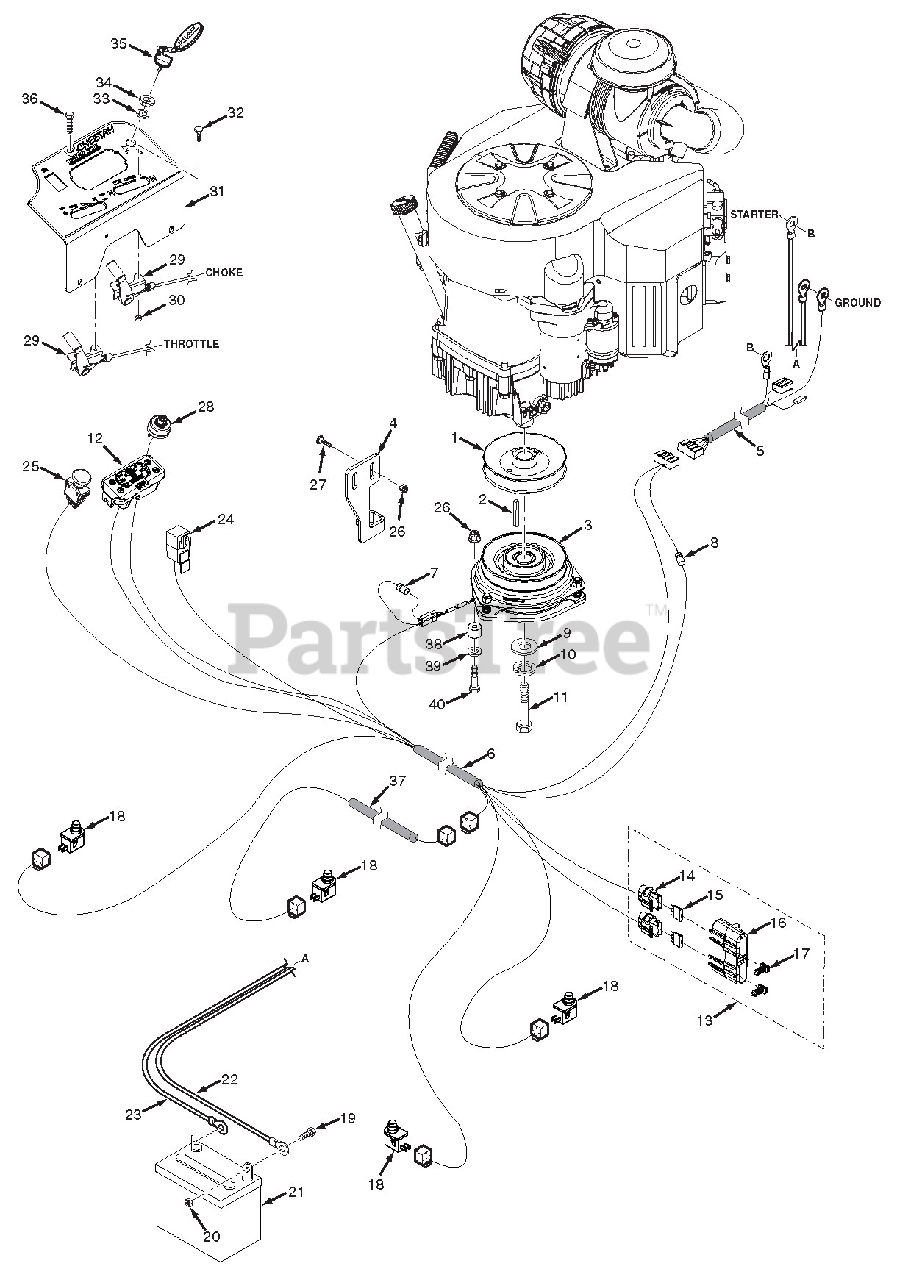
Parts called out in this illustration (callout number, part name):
1	Pulley, 5.80 Dia. - 1.125 Bore
2	Key, 1/4 x 1/4 x 3-1/4"
3	Electric Clutch w/Tag - GT-3.5 (FX850)
3	Electric Clutch w/Tag - GT-5 (FX921)
4	Bracket, Anti-Rotation
5	Wire Harness Adapter, Kawasaki
6	Wire Harness, SCZ
7	Diode, 600V - 6A
8	Diode
9	Flatwasher, 7/16-.469 x 1.75 x .25
10	Lockwasher, 7/16" Spring
11	Bolt, Hex Head 7/16-20 x 2-1/4" w/Patch (Kawasaki)
12	Tiger Eye Cluster Gauge
13	Double Fuse Assembly
14	Fuse Holder
15	Fuse, 20 Amp
16	Cover, Sealed Double
17	Clip, Wire
18	Switch, N.O.
19	Bolt, Hex Head 1/4-20 x 1/2"
20	Nut, 1/4-20
21	Battery
22	Battery Cable, 27" Black
22	Battery Cable, 18" Black (Kohler)
23	Battery Cable, 25" Red
24	Relay
25	Switch, PTO - 10 Amp
26	Nut, FLF HH Elastic Stop 5/16-18
27	Bolt, Carriage 5/16-18 x 1"
28	Keyswitch w/Hardware
29	Control Cable (Kawasaki FX850 Throttle & Choke Cable)
29	Control Cable (Kawasaki FX921 Throttle & Choke Cable)
30	Nut, Elastic Stop #10-24
31	Instrument Panel w/Decal
32	Bolt, Carriage #10-24 x 1/2"
33	Lockwasher, 5/8" Internal
34	Nut, Hex 5/8-32
35	Key Assembly w/Fob
36	Bolt, Hex Head 1/4-20 x 1/2" Serrated Flange
37	Wire Harness, Operator Platform -SCZ
38	Bushing, UHMW
39	Flatwasher, 5/16-.375 x .875 x .083
40	Bolt, Hex Head 5/16-18 x 1-1/2"
